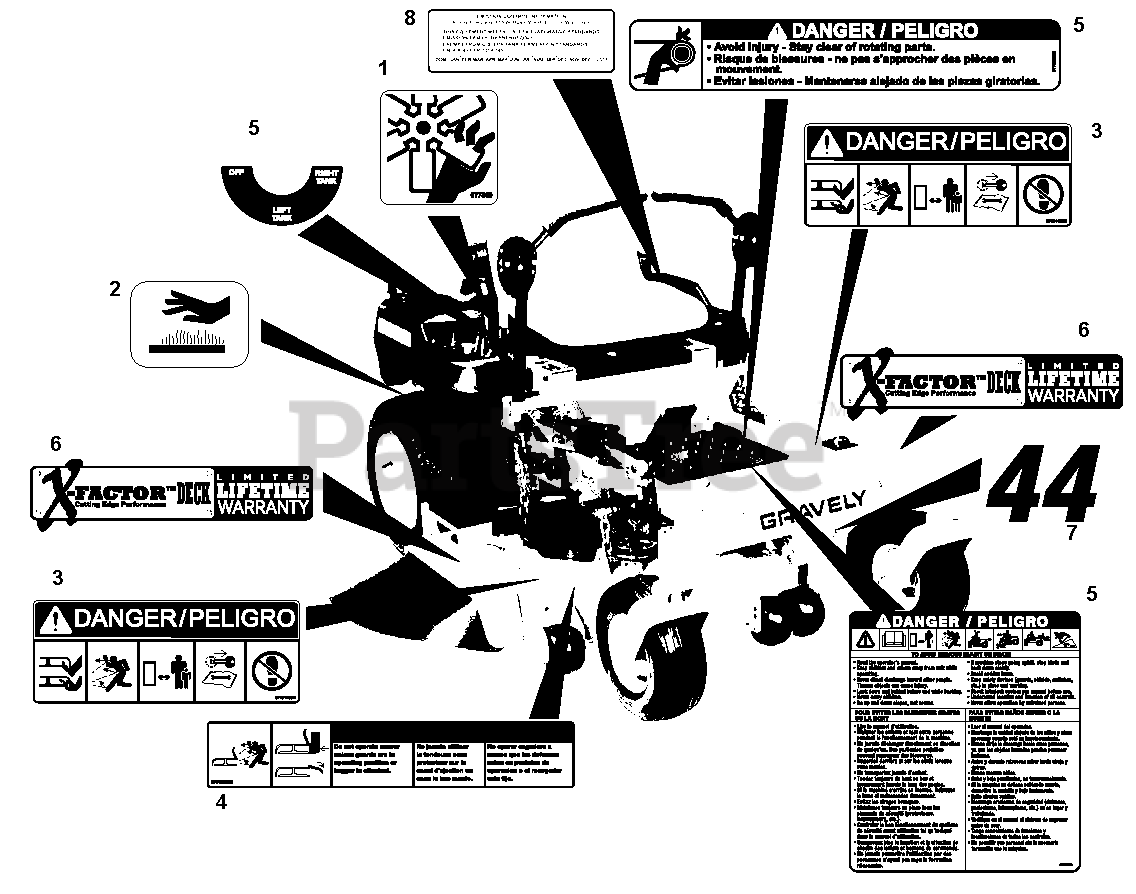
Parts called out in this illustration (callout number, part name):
1	Decal, Danger Fan
2	Decal, Hot Surface
3	Decal, Mower Pan Head Danger
4	Decal, Warning
5	Set, Decal Common Danger/Fuel
6	Decal, X-Factor Deck
7	Decal, 44
8	Decal, EPA Fuel (S/N 2500 and up)
